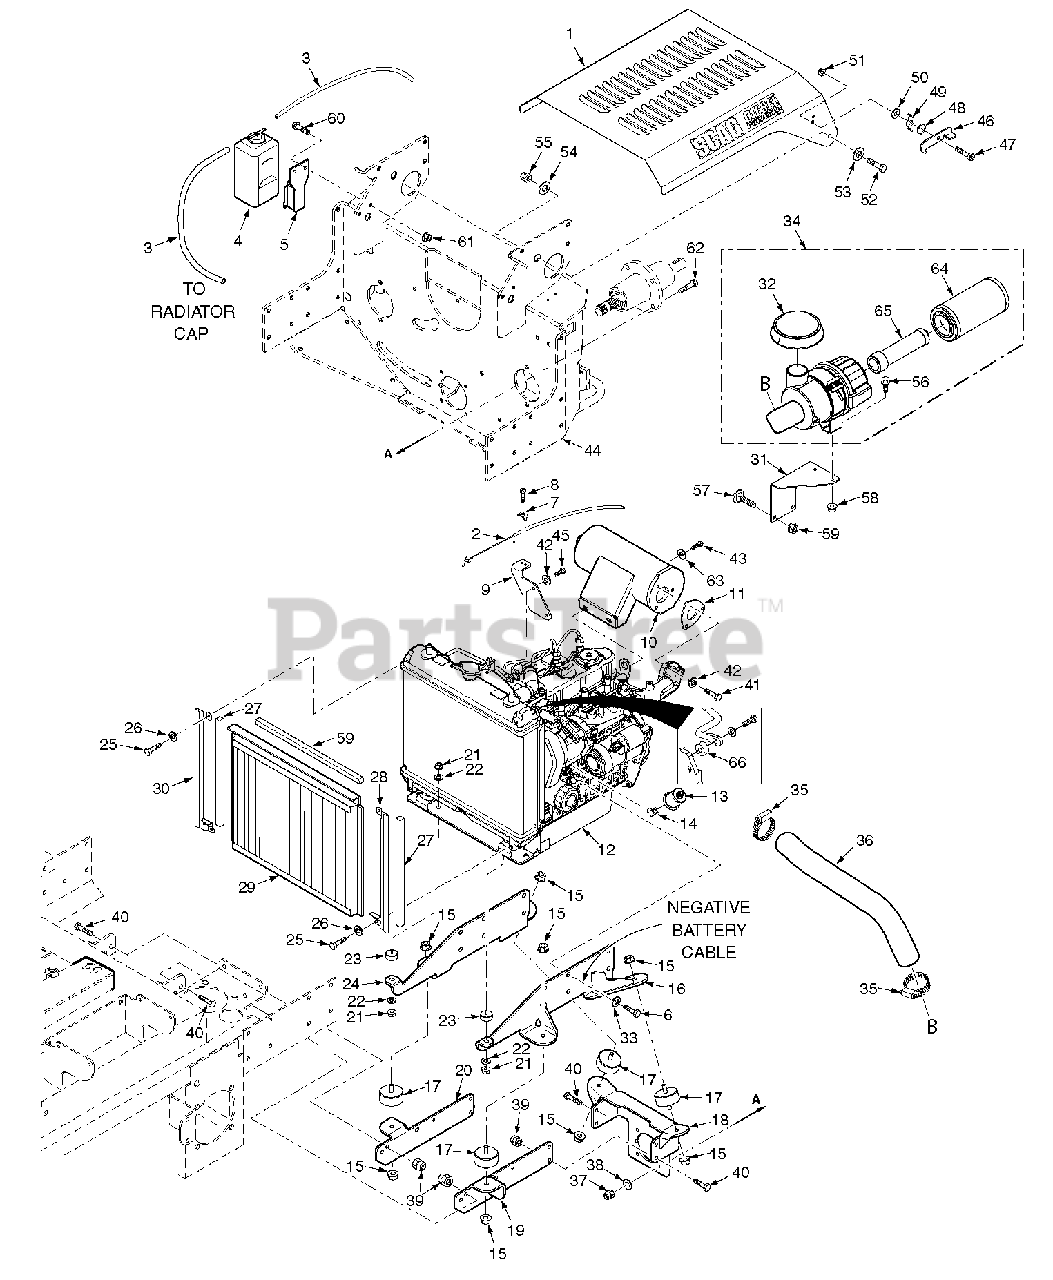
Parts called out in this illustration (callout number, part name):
1	Hood Assembly
2	Throttle Cable
3	Hose, Over Spill Bottle
4	Over Spill Bottle
5	Mounting Bracket, Over Spill Bottle
6	Bolt, Metric Hex Hd. M10-1.25 x 25mm
7	Clamp
8	Screw, Self Tapping
9	Bracket, Control Mount
10	Muffler, Kubota
11	Gasket, Muffler
12	Engine, Kubota (not avail. through Scag)
13	Oil Pressure Sender
14	Elbow, 45 Deg.
15	Nut, Serr. Flng. 5/16-18
16	Mounting Bracket Weldment LH
17	ISO Mount
18	Plate, Rear Engine Mount
19	Plate, Engine Mount LH
20	Plate, Engine Mount RH
21	Nut, Metric Hex M8-1.25mm
22	Lockwasher, 5/16" Spring
23	Rubber ISO Mount, Radiator
24	Mounting Bracket Weldment RH
25	Capscrew, Metric M6-1.0 x 16mm
26	Lockwasher, 1/4" Spring
27	Foam, Radiator Screen
28	Debris Screen Track LH
29	Debris Screen Assembly
30	Debris Screen Track RH
31	Bracket, Air Cleaner Mount
32	Rain Cap (Enginaire p/n 68381)
33	Lockwasher, 7/16" Spring
34	Air Filter Assembly (Enginaire p/n 68665)
35	Clamp, 2-1/4" Max. Dia.
36	Hose, Air Intake
37	Nut, Elastic Stop 5/16-18 Grd. 8
38	Lockwasher, 5/16" Spring
39	Nut, Elastic Stop 3/8-16
40	Bolt, Hex Hd. 3/8-16 x 1"
41	Bolt, Metric Hex Hd. M8-1.25 x 30mm
42	Lockwasher, 5/16" Spring
43	Bolt, Metric Hex Hd. M8-1.25 x 25mm
44	Pump Mounting Plate Weldment (Kubota)
45	Bolt, Metric Hex Hd. M8-1.25 x 20mm
46	Latch, Hood
47	Bolt, Shoulder 5/16-18 x 1/2"
48	Spring, Hood Latch
49	Lock, Hood Latch
50	Flatwasher, 3/8 (.391 x .938 x .105")
51	Nut, Center Lock 5/16-18
52	Bolt, Hex Hd. 3/8-16 x 1-3/4"
53	Flatwasher, 3/8 (.391 x .938 x .105")
54	Flatwasher, 3/8 (.406 x 1.50 x 7 Ga.)
55	Nut, Elastic Stop 3/8-16
56	Bolt, Hex Hd. Serr. Flng. 5/16-18 x 3/4"
57	Bolt, Carriage 5/16-18 x 3/4"
58	Nut, Serr. Flng. 5/16-18
59	Foam, Radiator Screen Upper
60	Bolt, Hex Hd. Serr. Flng. 5/16-18 x 3/4"
61	Nut, Serr. Flng. 5/16-18
62	Bolt, Hex Hd. 5/16-18 x 1-3/4" Grd. 8
63	Flatwasher, SAE 5/16 (.344 x .688 x .065")
64	Air Filter, Outer (Enginaire p/n 68300)
65	Air Filter, Inner (Enginaire p/n 68340)
66	Spacer, Radiator
